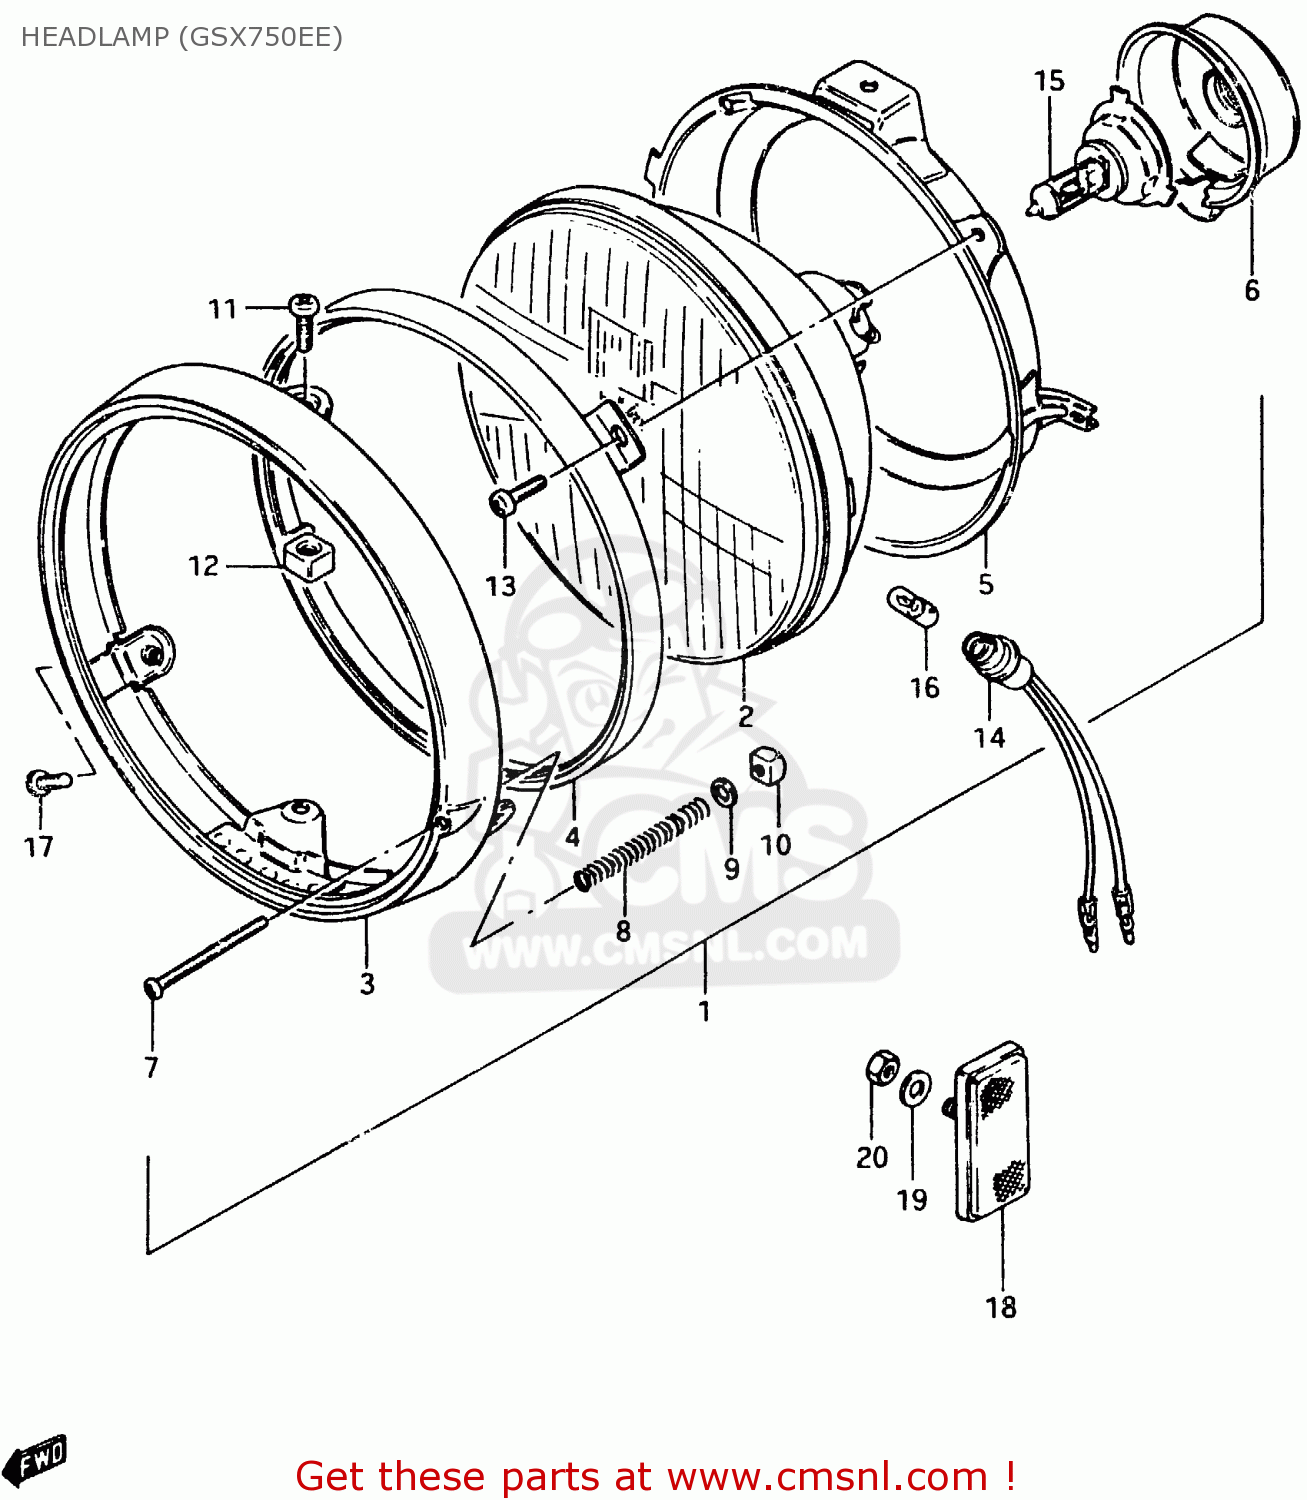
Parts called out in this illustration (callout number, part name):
1	HEADLAMP ASSY
2	UNIT
3	RIM
4	RETAINER
5	RING,MOUNTING
6	COVER,HEADLAMP SOCKET
7	SCREW
8	SPRING,HEADLAMP ADJUST
9	WASHER
10	NUT
11	SCREW
12	NUT
13	SCREW
14	SOCKET,PARKING
15	BULB(12V60/55W,H4)
16	BULB(12V4W)
17	SCREW(5X12)
18	REFLEX REFLECTOR, FRONT SIDE
19	WASHER,5MM
20	NUT ,5MM
